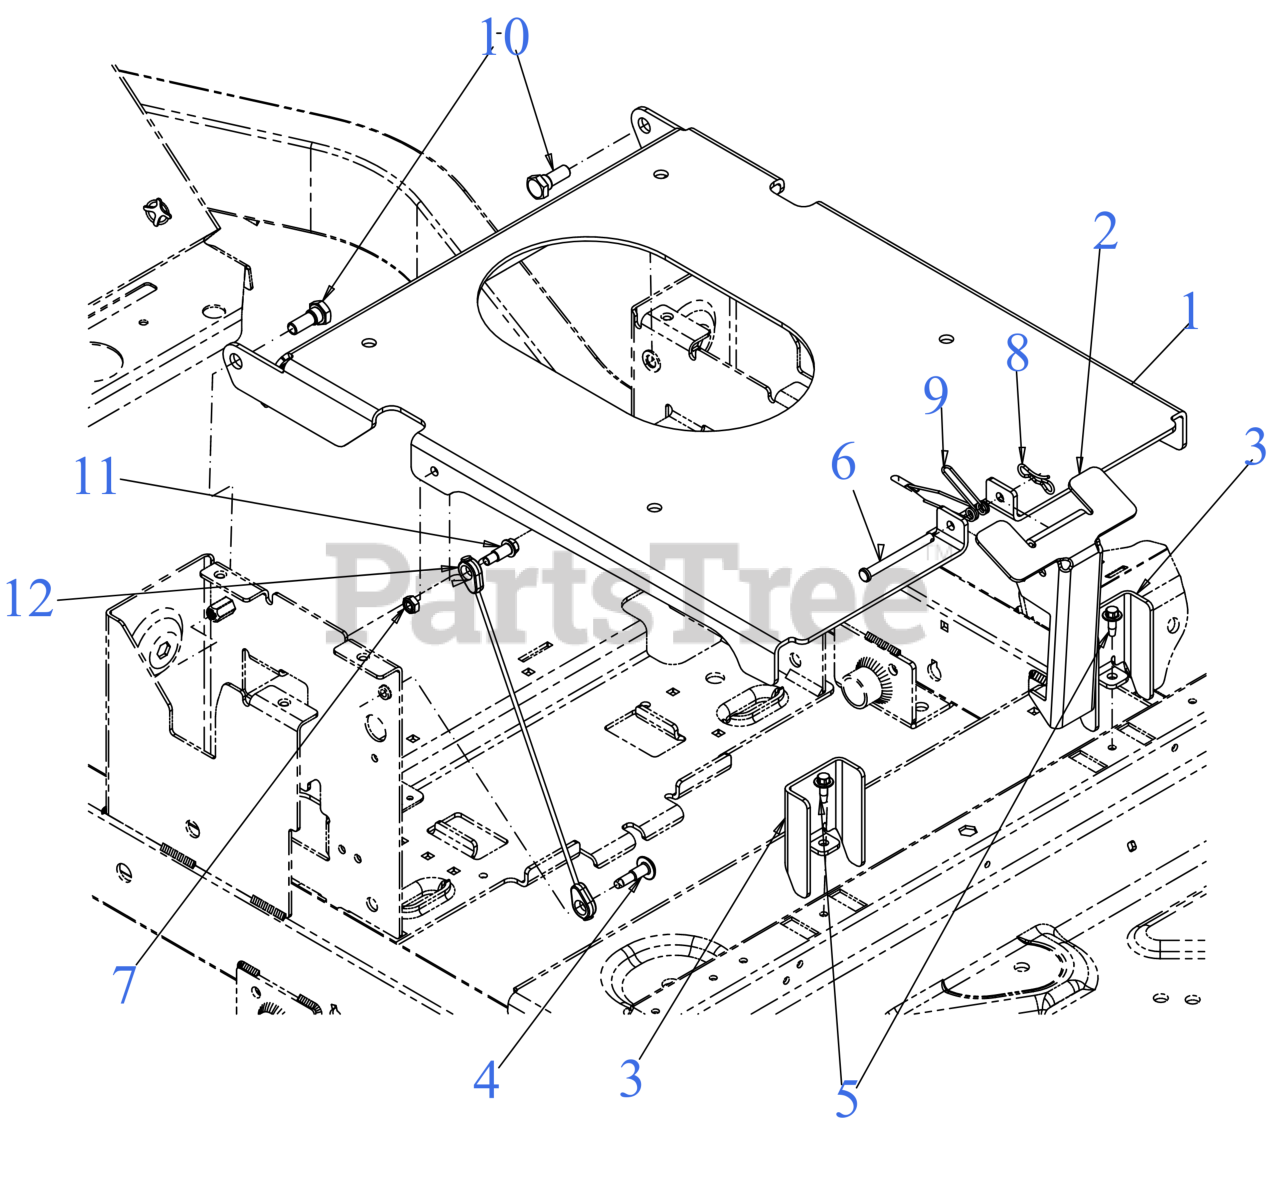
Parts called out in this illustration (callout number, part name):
1	SEAT BASEPLATE
2	SEAT LATCH BRACKET
3	SEAT SUPPORT
4	BOLT 1/4-20
5	SCREW M6-1 x .625
6	CLEVIS PIN .248 x 2.345
7	HEX NUT 1/4-20
8	BOW TIE COTTER PIN 1/4-5/16
10	SHOULDER SCREW .437
11	SHOULDER SCREW
12	SEAT BASE CABLE 10"
